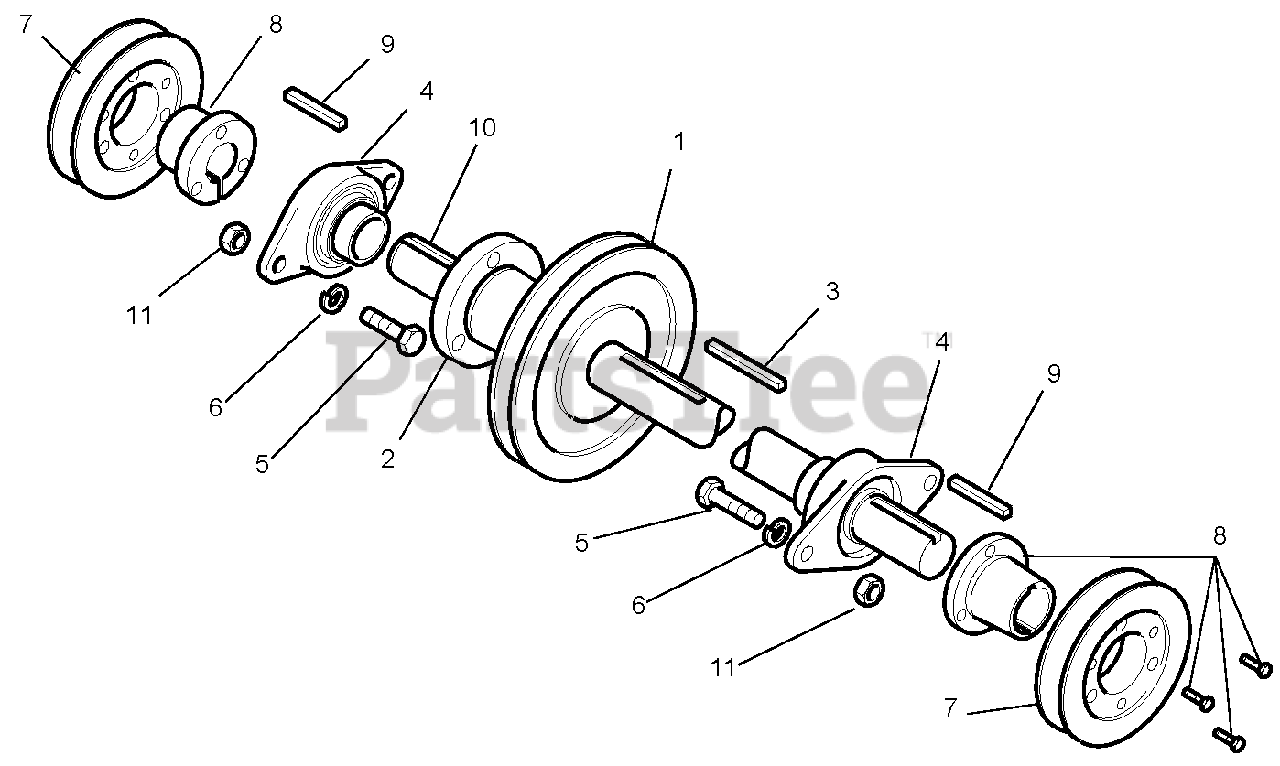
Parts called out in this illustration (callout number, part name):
1	Pulley, 1-Belt 6.6 PD
2	Bushing, Split Tapered
3	Key, Pulley
4	Bearing Flange, 2-Bolt
5	Cap Screw, Hex Head .437-14 x 1.25
6	Washer, Lock .437
7	Pulley, 1-Belt 4.4 PD
8	Bushing, Split Tapered
9	Key, Square .25 x .25 x 1
10	Jackshaft, Front
11	Nut, Hex .437
